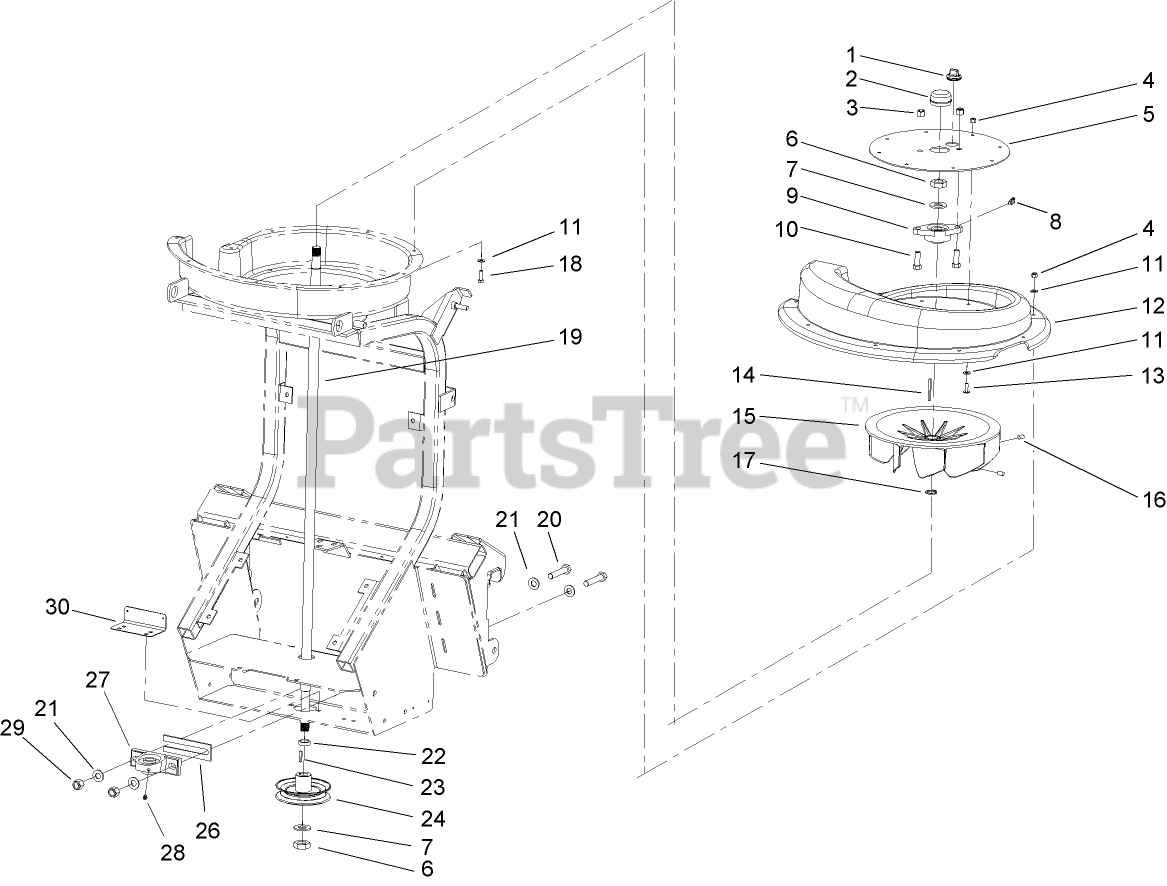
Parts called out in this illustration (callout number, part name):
2	CAP-GREASE
3	NUT-LOCK, NI
4	NUT-LOCK, NI
5	COVER-SCROLL
6	NUT-HEX
7	WASHER
8	FITTING-LUBE, 45 DEG
9	BEARING-FLANGE
10	SCREW-HH
11	WASHER-FLAT
12	SCROLL-TOP
13	SCREW-HEAD, TRUSS
14	KEY-SQUARE
15	FAN-BALANCING
16	SCREW-SET
17	RING-RETAINING, Ext
18	SCREW-HH
19	SHAFT-FAN
20	SCREW-HH
21	WASHER-FLAT
22	Spacer
23	KEY-SQUARE
24	Pulley-V
26	SPACER-BEARING
27	BEARING
28	FITTING-GREASE
29	NUT-LOCK, NI
30	TEMPLATE, BASE FRAME
